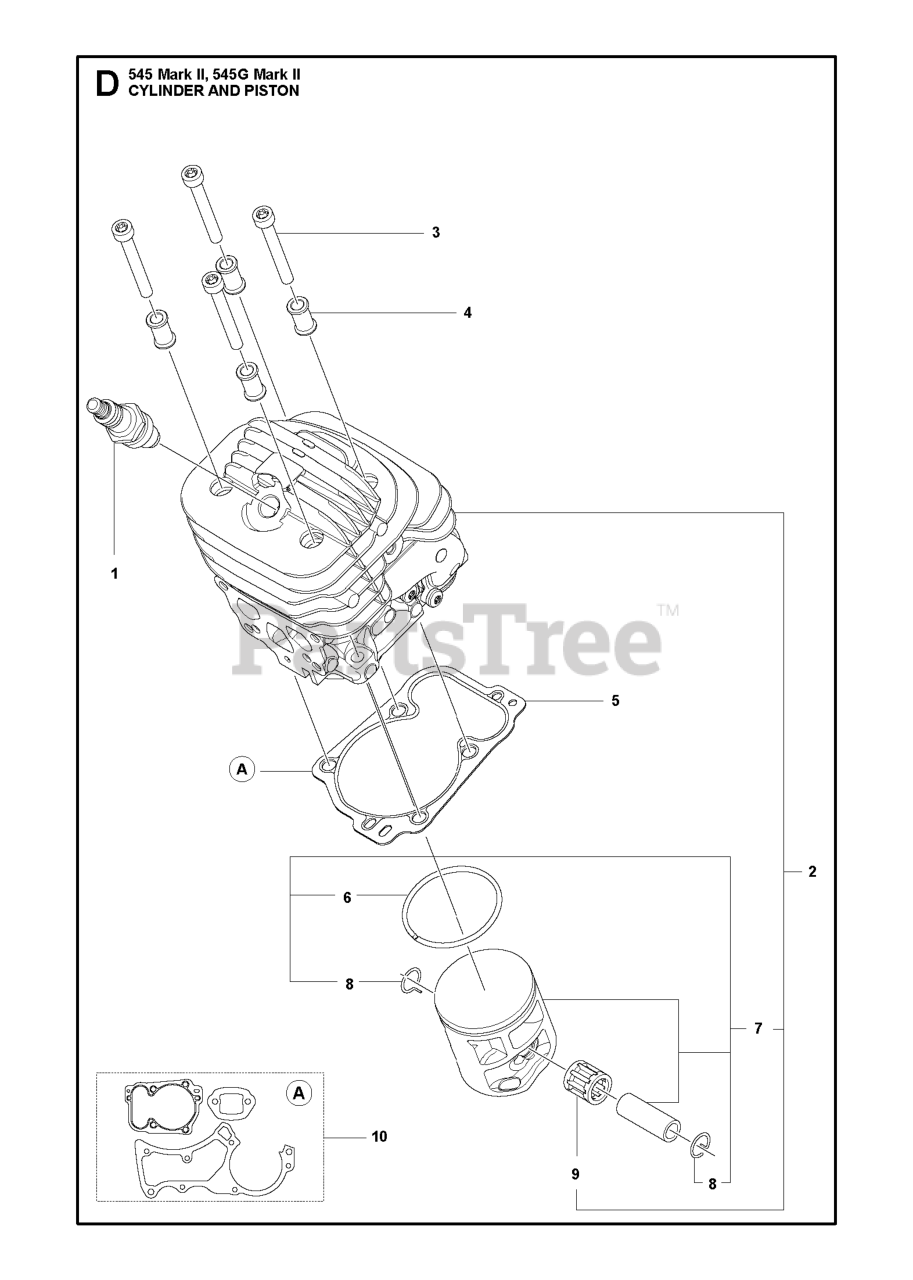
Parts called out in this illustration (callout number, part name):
1	CMR6H SPARK PLUG NGK
2	CYLINDER KIT D43 H545 SPARE PA
3	SCREW ITXSCM
5	GASKET CYLINDER BASE GASKET
6	PISTON RING D43 G2
7	PISTON ASSY
8	LOCKING RING
9	NEEDLE BEARING
10	GASKET KIT MARK II
